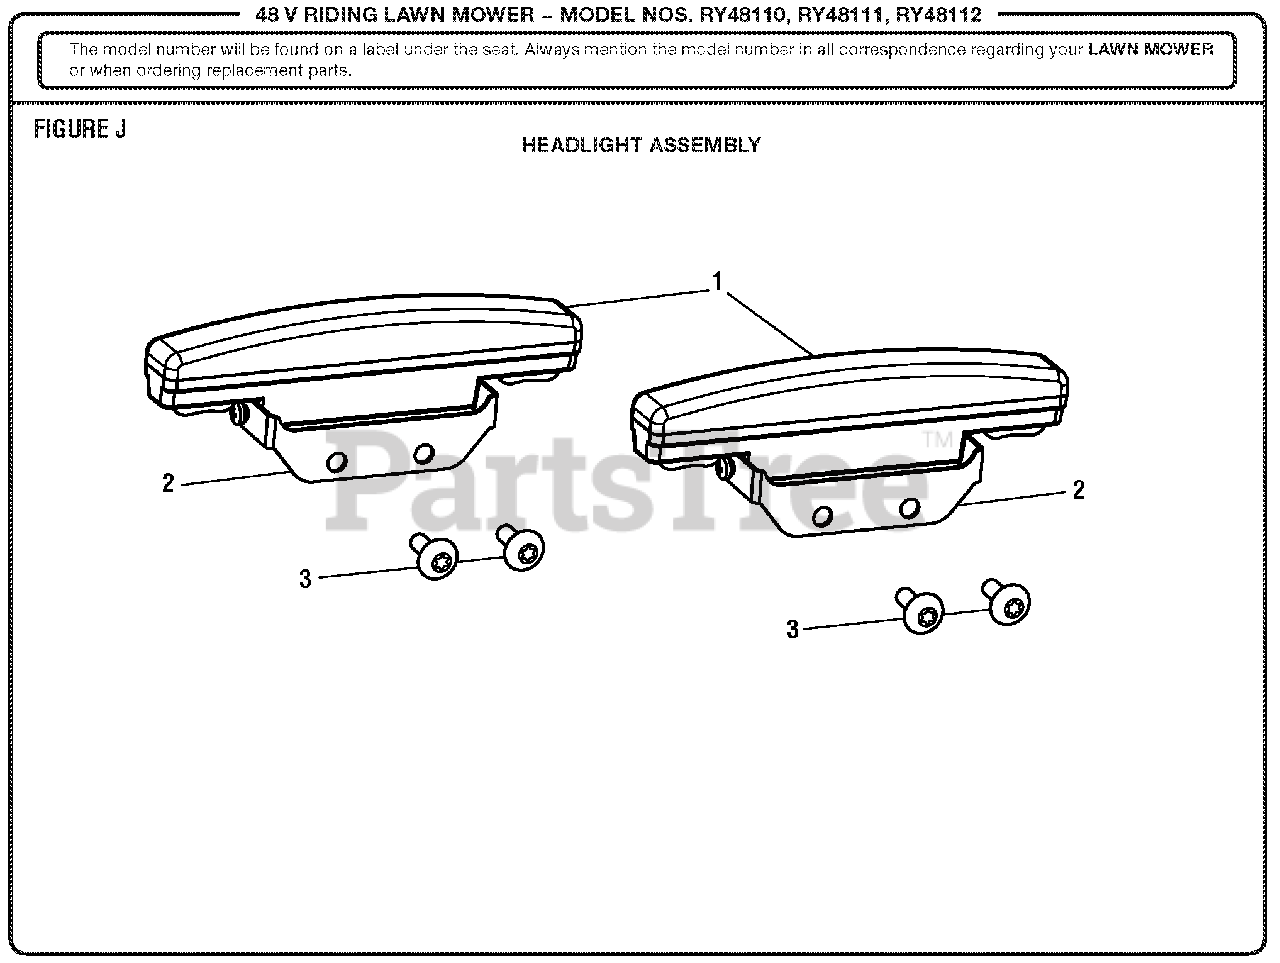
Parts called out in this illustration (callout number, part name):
1	Light Assembly
2	Bracket (Bracket Only)
3	Screw (M6 x 16, Torx. Pan Hd.)
